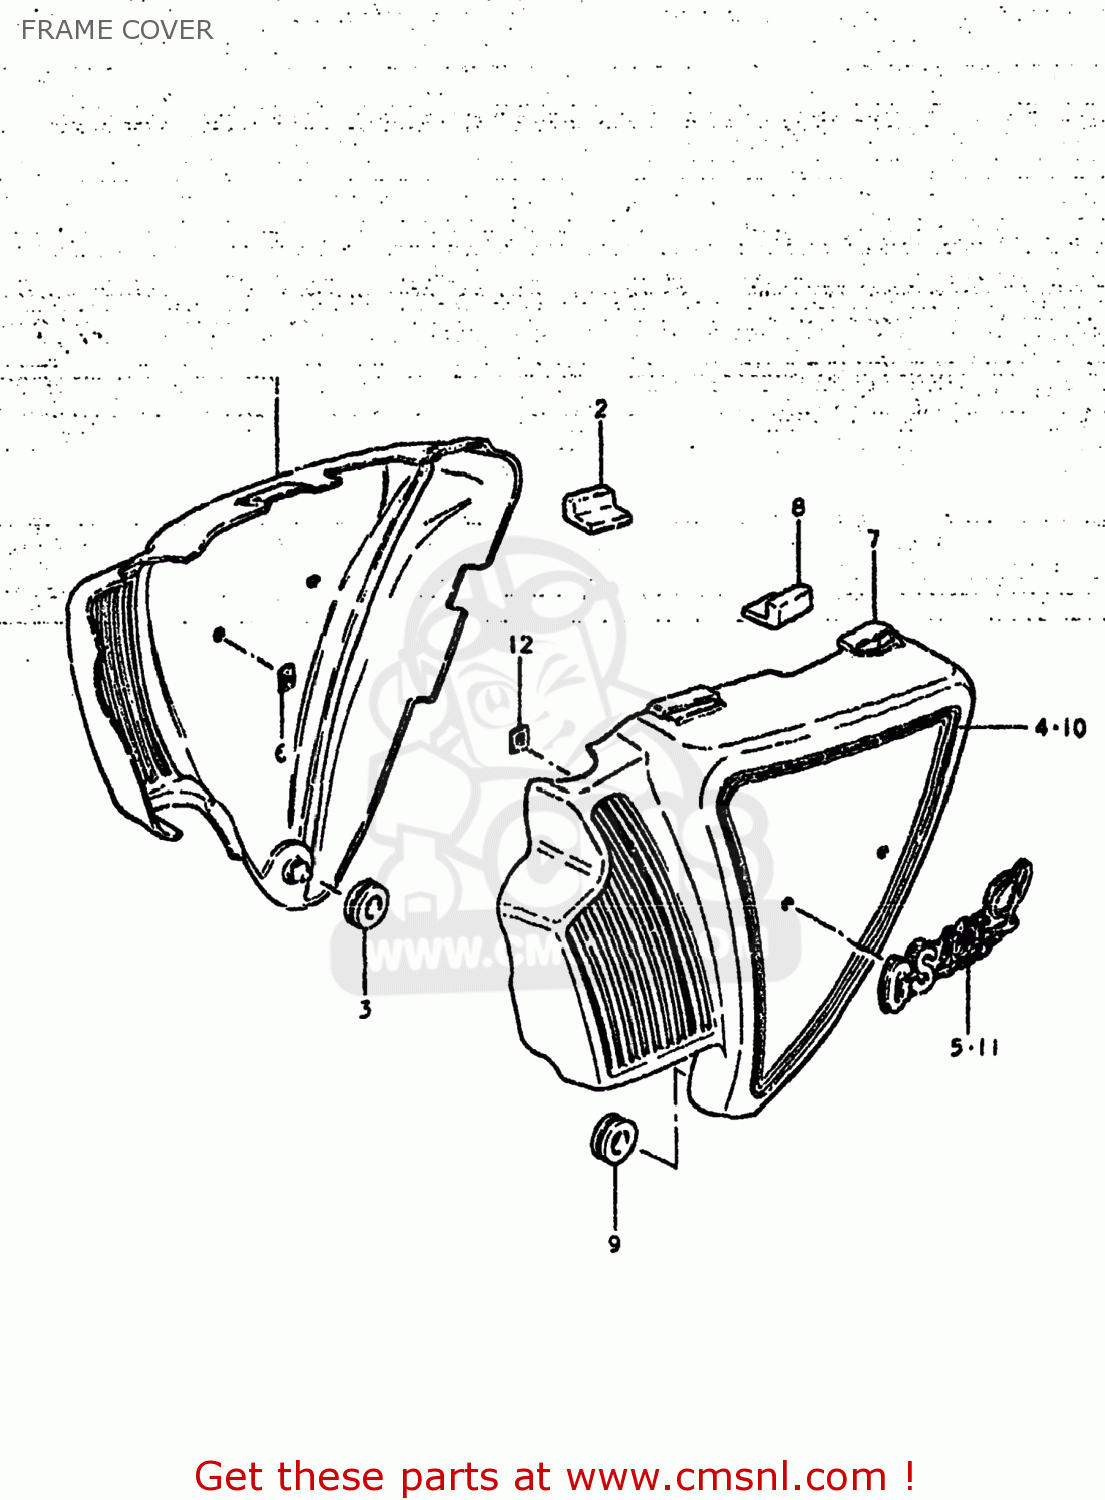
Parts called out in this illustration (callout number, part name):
1	COVER,FRAME,RIGHT
2	CUSHION,FRAME COVER
3	CUSHION
4	TAPE SET
5	EMBLEM
6	NUT
7	COVER,FRAME,LEFT
8	CUSHION,FRAME COVER
9	CUSHION
10	TAPE SET
11	EMBLEM
12	NUT
